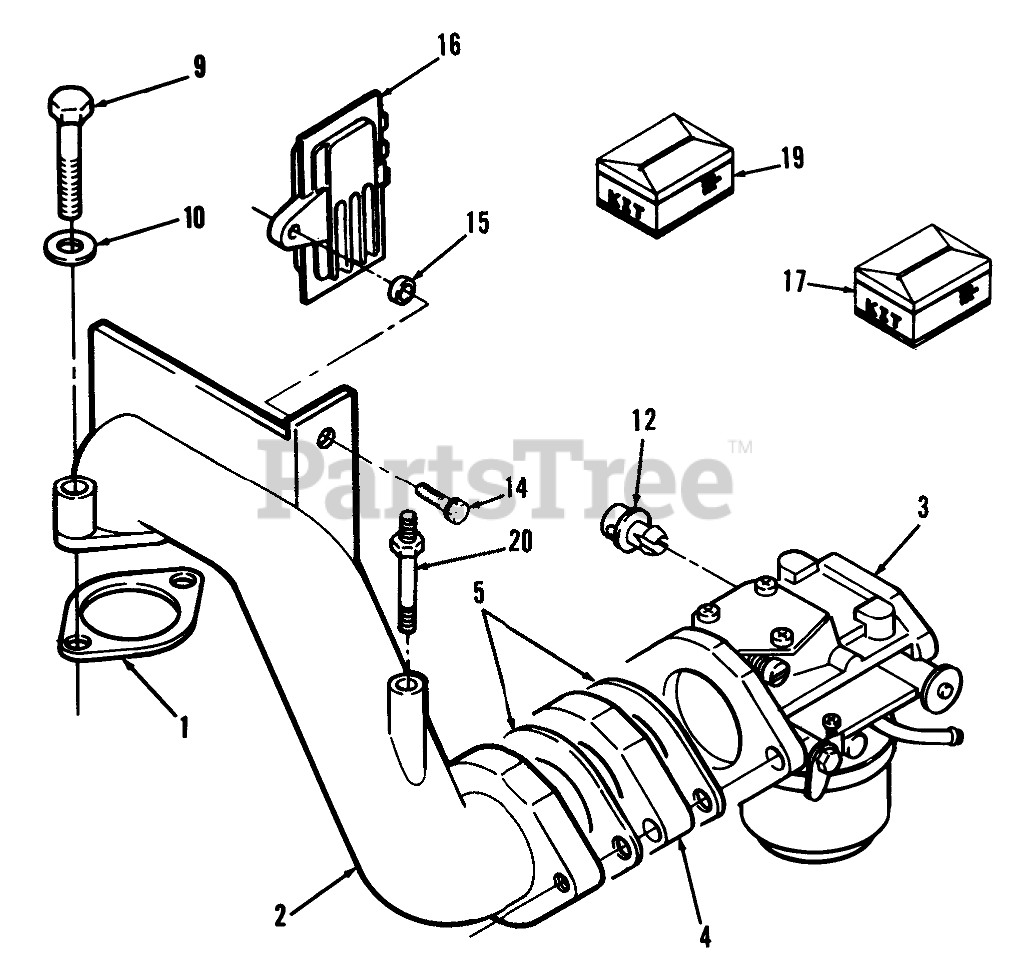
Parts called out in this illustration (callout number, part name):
1	Gasket
2	ELBOW-INTAKE
3	CARBURETOR
4	INSULATOR
5	Gasket
9	SCR-HHC (M8X50)
10	WASHER-FLAT (M8)
12	Clip
14	Bolt 1/4-20 x 2
15	BUSHING
16	REGULATOR
17	FLOAT-KIT
19	CARB-REBUILD KIT
